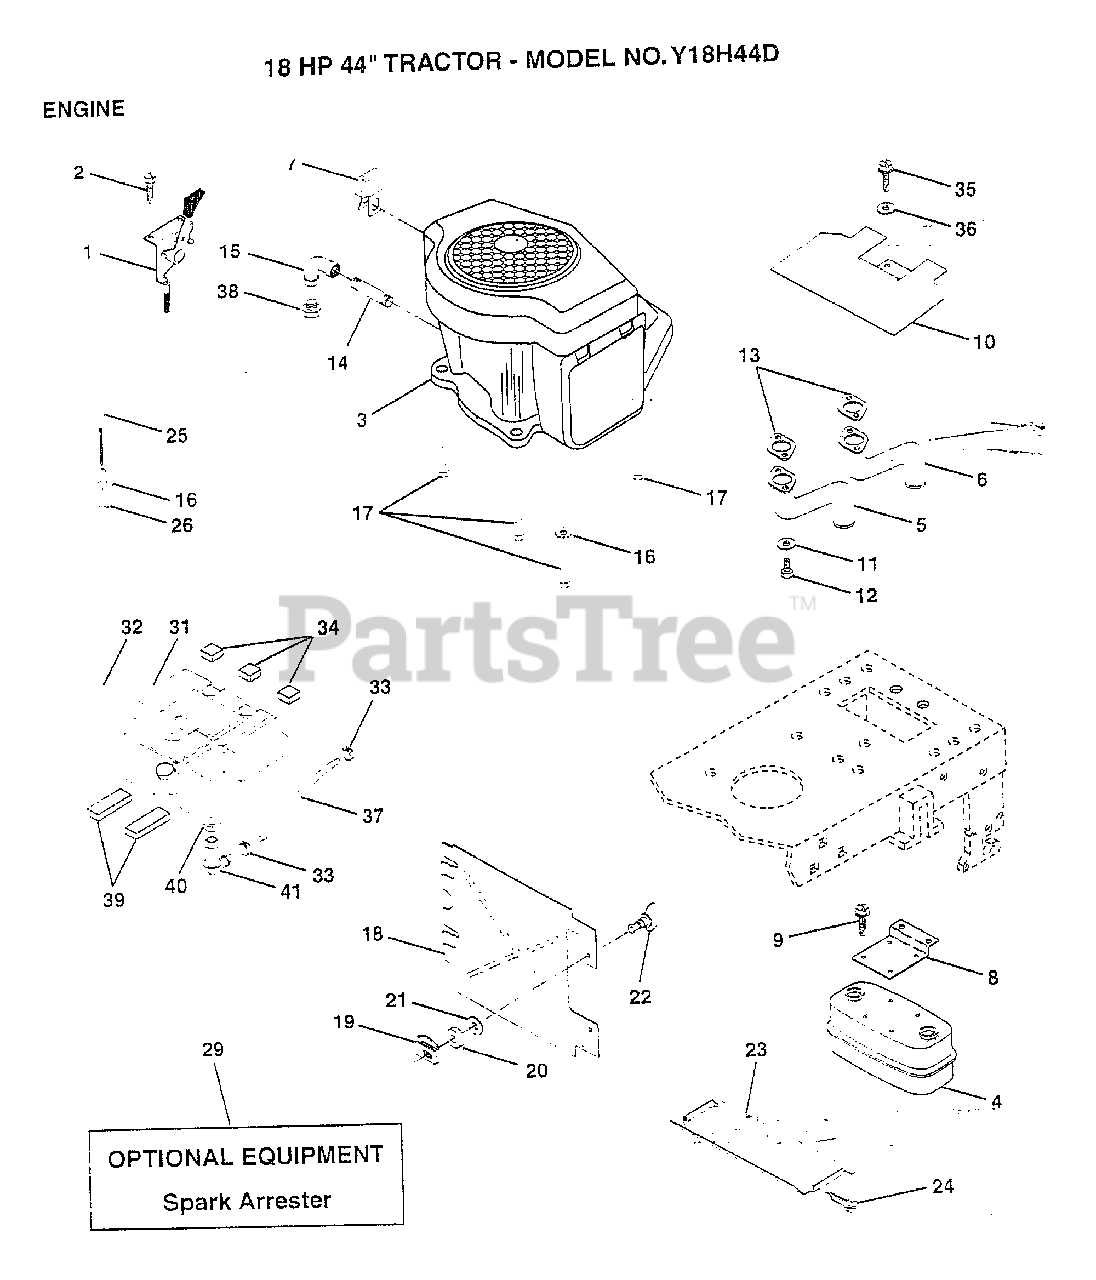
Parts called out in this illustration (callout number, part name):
1	CONTROL.THROTTL
2	SCREW LT
5	"TUBE,MANIFOLD LH"
6	"TUBE,MANIFOLD RH"
7	CLIP T
8	BRACKET MUFFLER
9	SCREW ST
10	SHIELD HEAT LT
11	LOCKWASHER
12	SCREW
14	PIPE NIPPLE LT
15	ELBOW
16	LOCKWASHER
17	SCREW LT
18	HEAT SHIELD
19	RECEPTACLE LT
20	RETAINER LT
22	STUD.1/4.TURN
23	HEAT SHIELD
24	SCREW
32	CAP ASM FUEL
33	HOSE CLAMP
34	PAD-SPACER LT
35	SCREW
36	WASHER
37	FUEL LINE T
39	PAD IDLER TI
40	BUSHING OUTLET T
